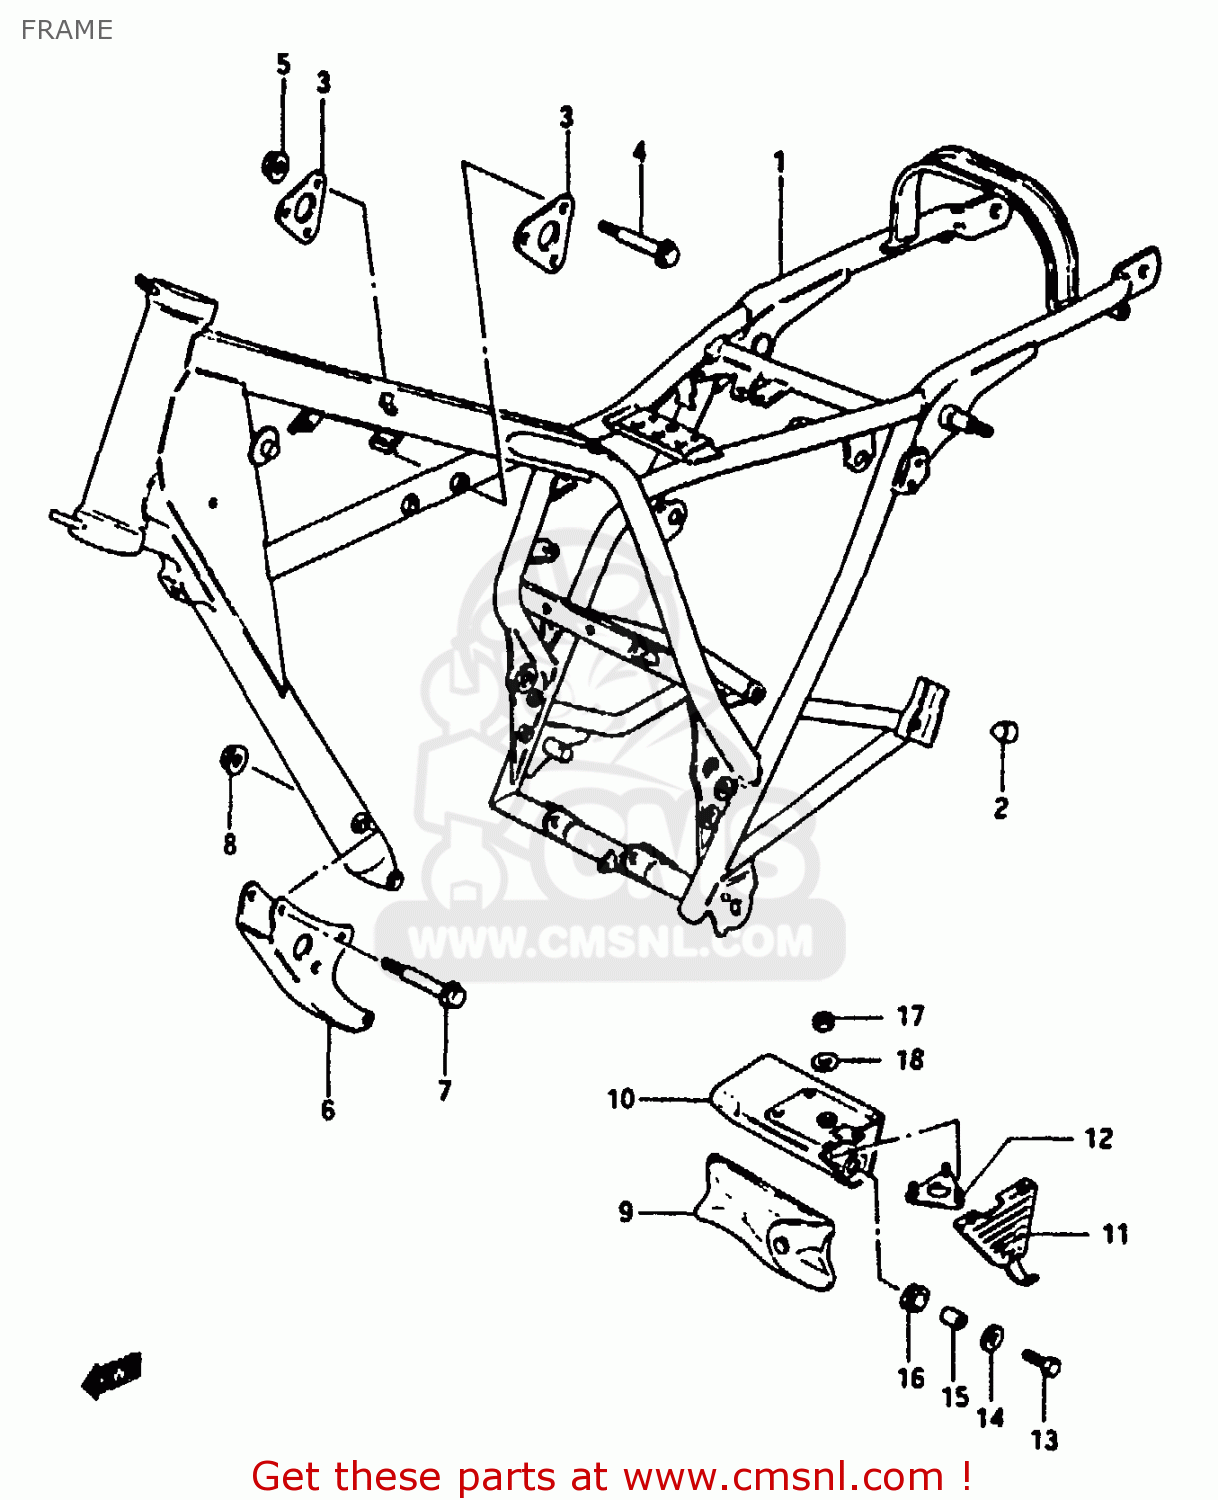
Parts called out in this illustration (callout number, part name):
1	FRAME(BLACK)
2	CAP
3	PLATE,ENGINE MOUNT UPR
4	BOLT
5	NUT
6	PLATE,ENGINE MOUNTING
7	BOLT
8	NUT
9	TOOL SET
10	BOX,TOOL
11	CAP,TOOL BOX
12	PLATE,TOOL HOLDER
13	BOLT
14	WASHER (6.5X20X1.2)
15	SPACER(6.1X9X7.5)
16	CUSHION
17	NUT 6MM
18	WASHER
